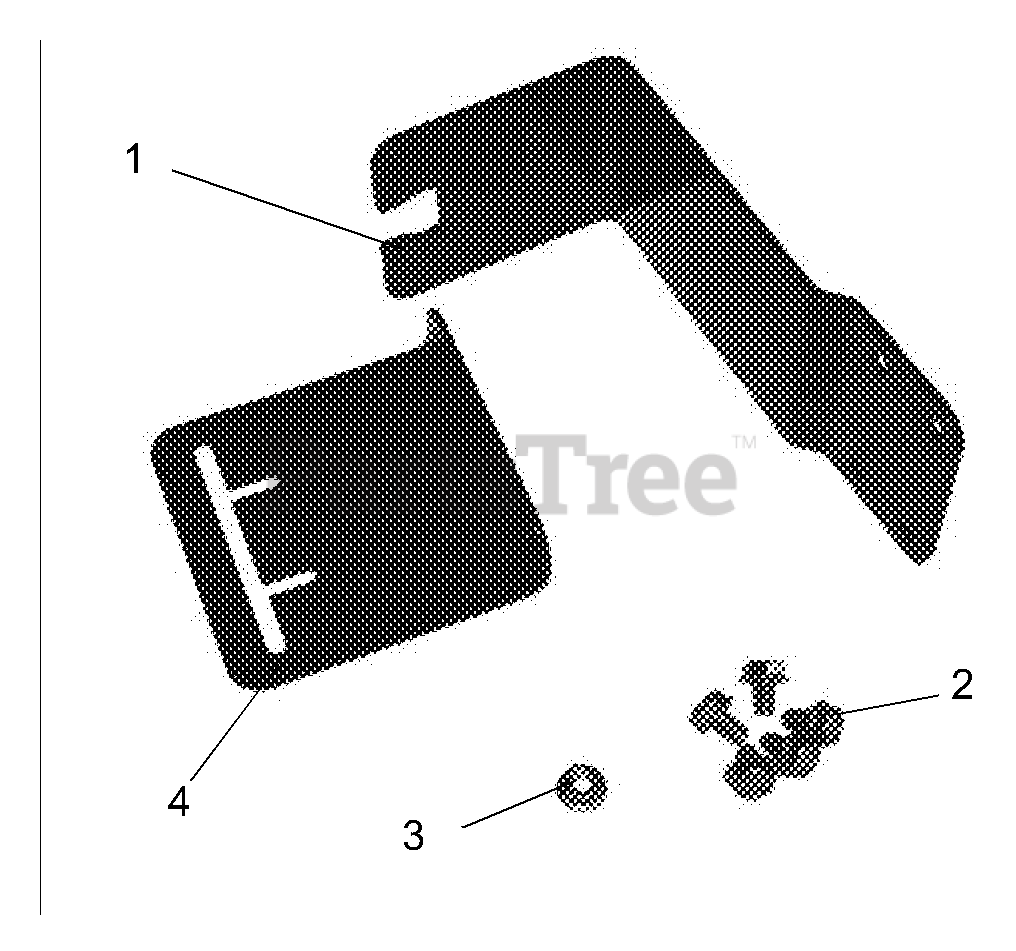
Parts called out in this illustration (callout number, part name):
1	MOUNT,FUEL TANK
2	@SCR-TAP .31-18X.50 HWH TR YWZ
3	@NUT-LK-TOP-FLG .31-18 YWZC
4	BKT,FUEL TANK
